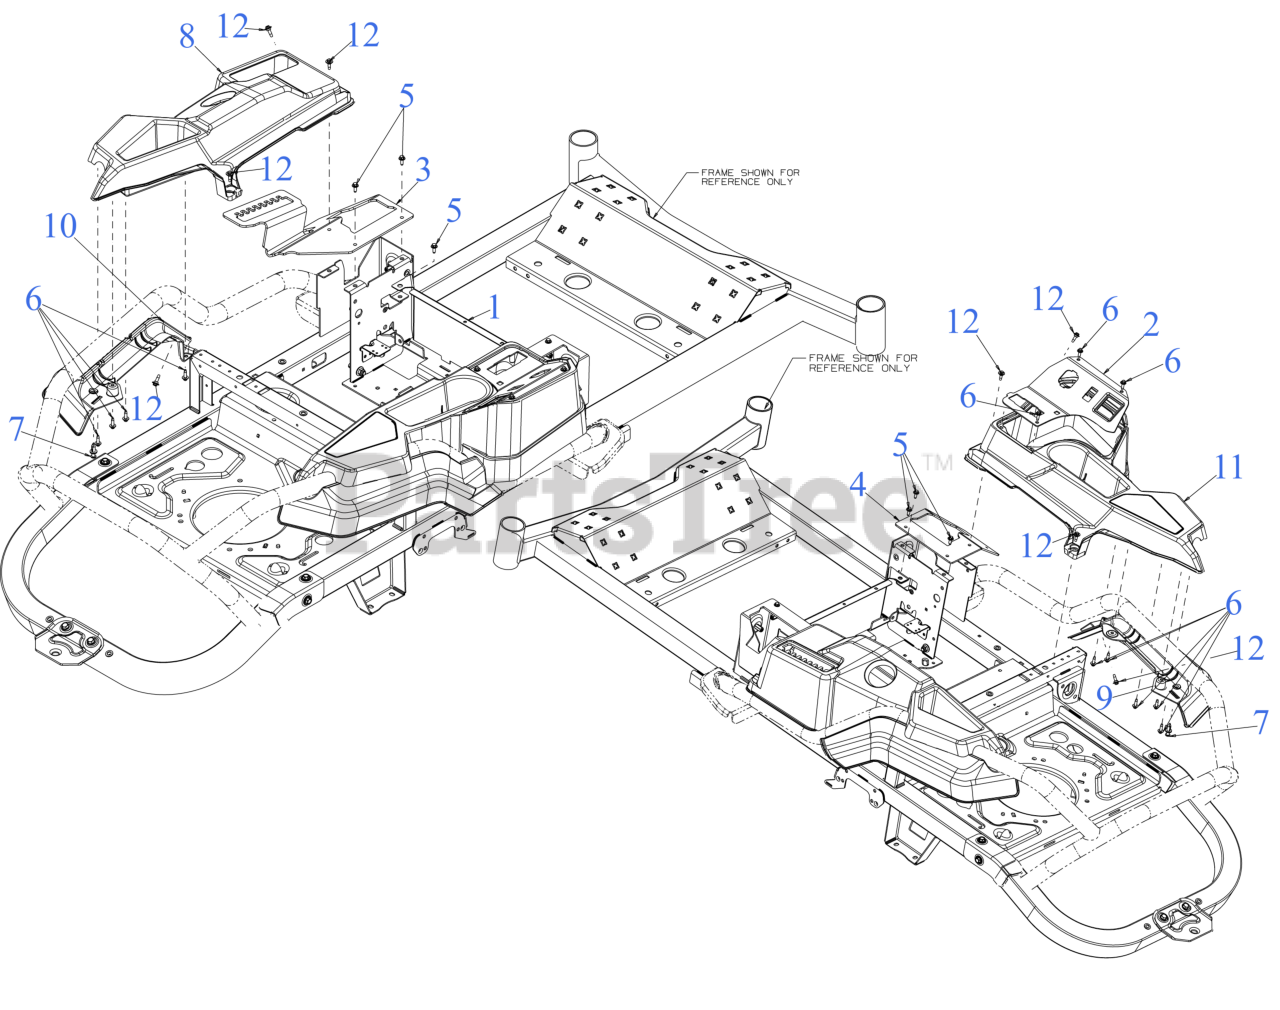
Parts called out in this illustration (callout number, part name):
1	SEAT BOX FRONT PLATE
2	CONSOLE COVER (RH)
3	CONTROL BRACKET (RED) (LH)
4	CONTROL BRACKET (RED) (RH)
5	SCREW M6-1 x .625
6	SCREW 1/4-10 x .750
7	PLASTIC RIVET
8	CONSOLE (LH)
9	FENDER CONSOLE (RH)
10	FENDER CONSOLE (LH)
11	CONSOLE (RH)
12	SHOULDER SCREW M6-1 .368 X.115
